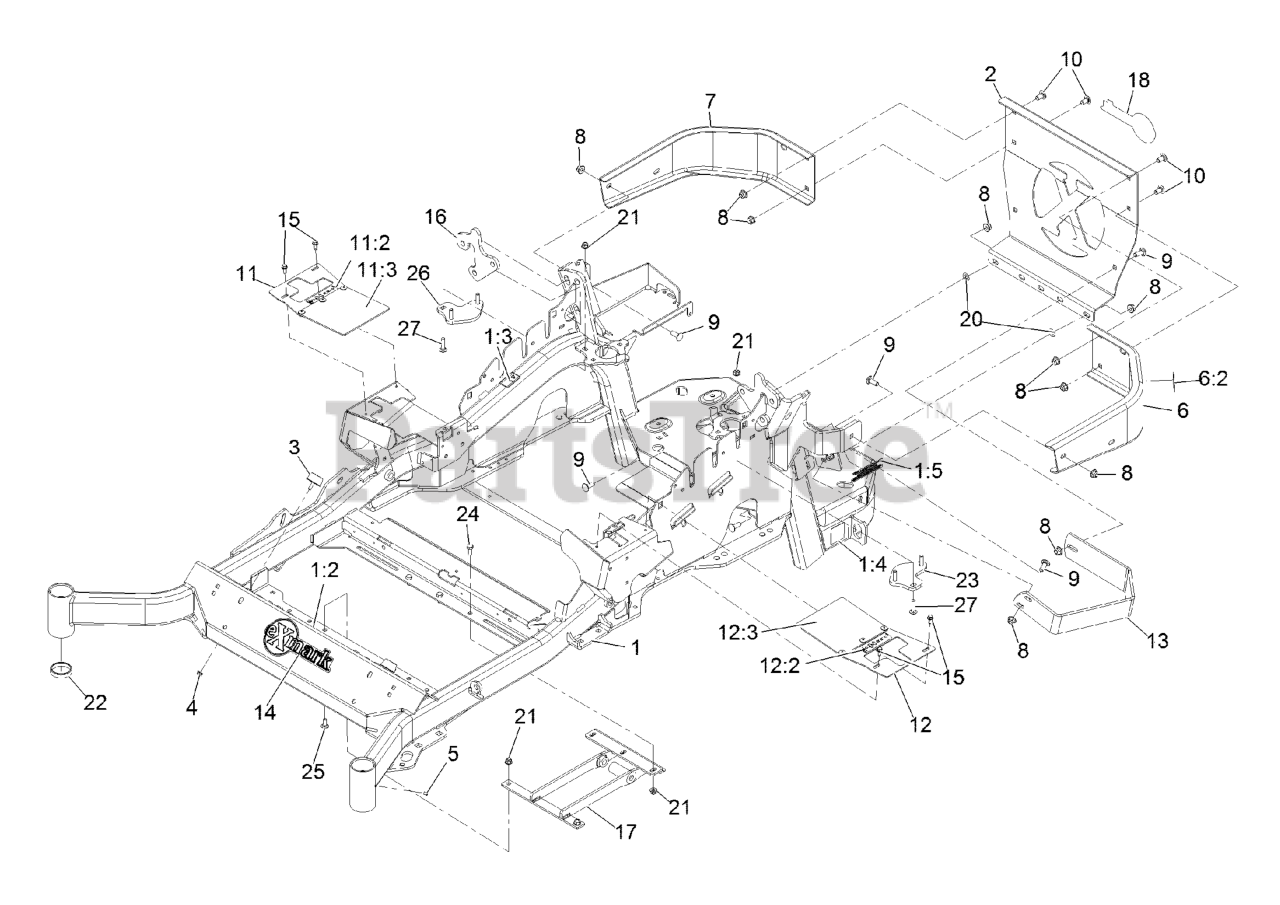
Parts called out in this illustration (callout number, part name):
1	MAINFRAME ASM
1:2	DECAL-DANGER
1:3	DECAL-WARNING
1:4	DECAL-HAZARD, PINCHED FINGER
1:5	DECAL-SPARK ARRESTER
2	PLATE,REAR GUARD
5	ROPS ASM
7	Caster Wheel ASM
9	LH BUMPER ASM
9:2	DECAL-WARNING
10	BUMPER-RH
11	NUT-HF, NI
12	SCREW-CARR
13	SCREW-CARR
14	RH MOTION CONTROL COVER A
14:2	DECAL-CONTROL, MOTION
14:3	FLAP-RUBBER
15	LH MOTION CONTROL COVER A
15:2	DECAL-CONTROL, MOTION
15:3	FLAP-RUBBER
16	GUARD-MUFFLER
17	DECAL-EXMARK LOGO
18	SCREW-HWH
19	LH HYDRO GUARD ASM
19:2	DECAL-OIL, HYDRO
20	RH HYDRO GUARD ASM
20:2	DECAL-OIL, HYDRO
21	GUARD-HYDRO, REAR (LH)
22	GUARD-HYDRO, REAR (RH)
26	DECAL-E-SERIES
30	DECAL-EXMARK LOGO
33	RIVET-POP
34	DEFLECTOR-AIR FLOW
69	NUT-PUSH
76	DECAL-FUEL FILL, CE
77	CUP-BEARING
80	Decal-Patent Ttco.Com
81	WEIGHT-TOE BOARD
82	SCREW-HH
83	WASHER-FLAT
